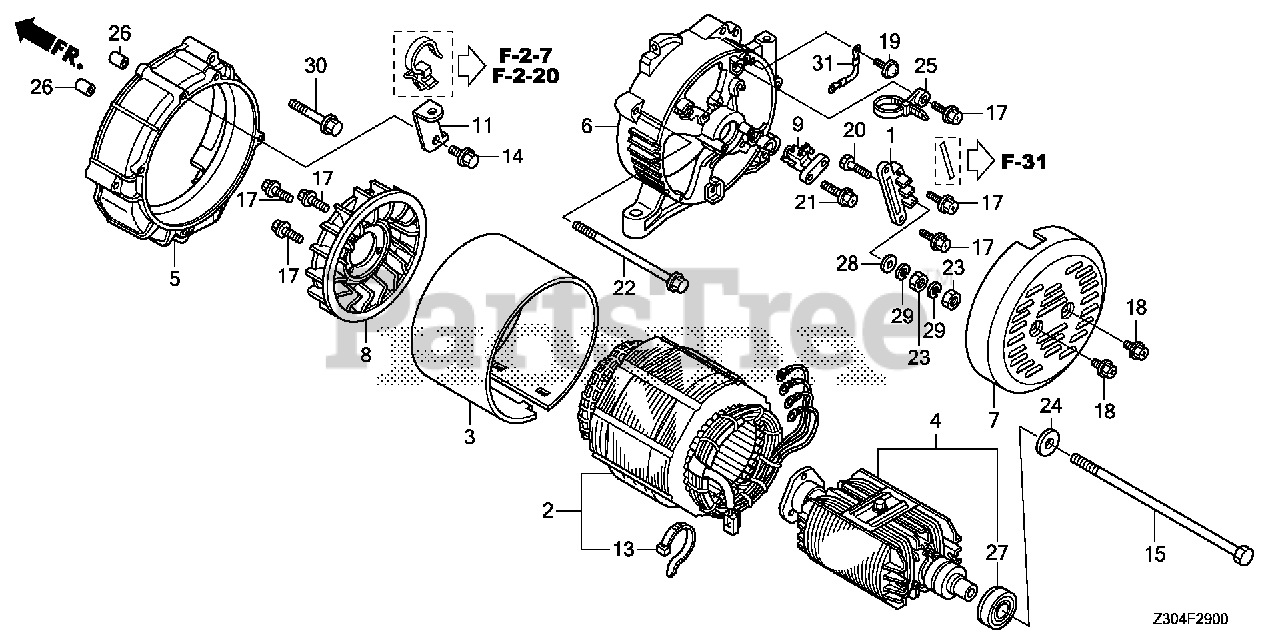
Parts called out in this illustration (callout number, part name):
1	TERMINAL, VOLT CHANGE
2	STATOR ASSY.
3	COVER, STATOR *NH105* (MAT BLACK)
5	HOUSING, FR.
6	HOUSING, RR.
7	COVER, GENERATOR END *NH105* (MAT BLACK)
8	FAN, GENERATOR COOLING
9	BRUSH ASSY.
11	BRACKET, WIRE HARNESS CLIP
13	TIE, CABLE (C)
14	BOLT, FLANGE (6X12) (CT200)
15	BOLT, HEX. (10X250)
17	SCREW, TAPPING (5X14)
18	SCREW, TAPPING (5X12)
19	SCREW, PAN (5X12)
20	BOLT, HEX. (5X20)
21	SCREW, TAPPING (5X18)
22	BOLT, FLANGE (6X160)
23	NUT, HEX. (5MM)
24	WASHER (10.5MM)
25	TIE, CABLE
26	PIN, DOWEL (8X12)
27	BEARING ASSY. (6204)
28	WASHER, PLAIN (5MM)
29	WASHER, SPRING (5MM)
30	BOLT, FLANGE (8X60)
